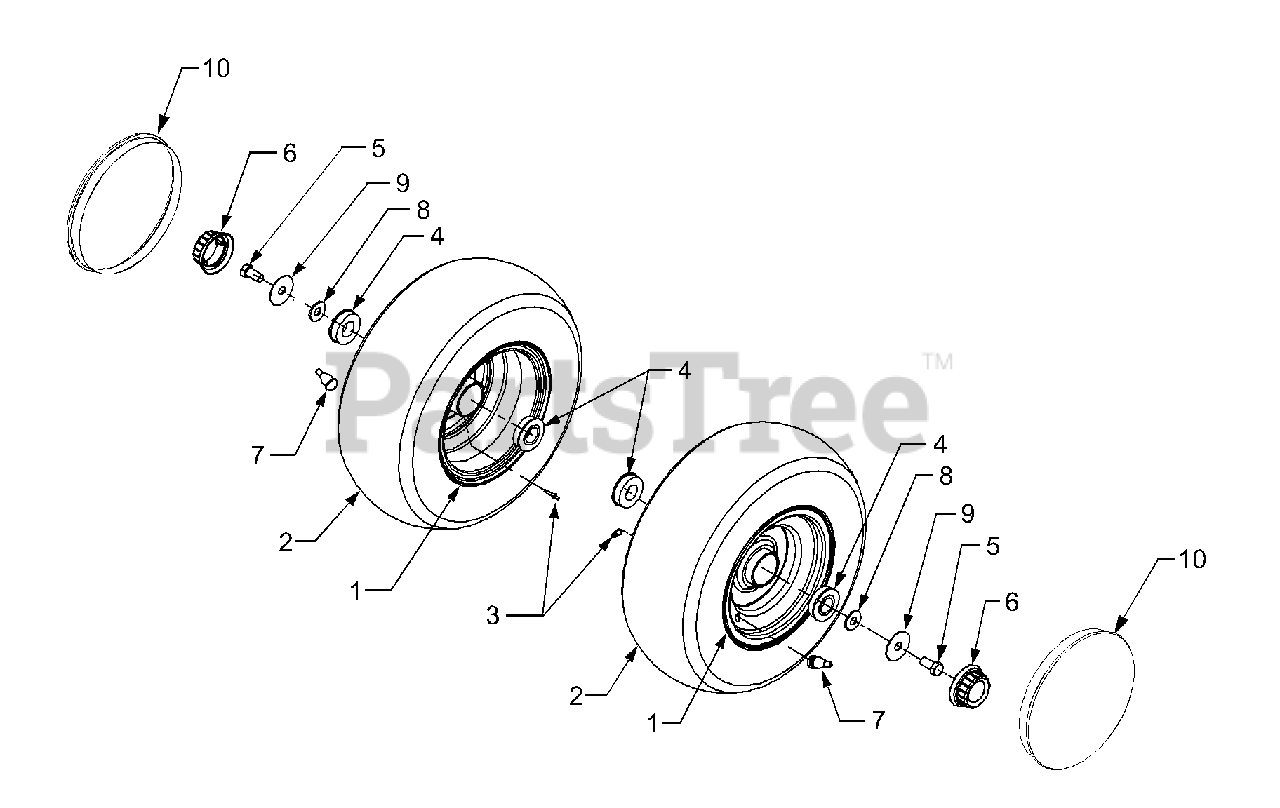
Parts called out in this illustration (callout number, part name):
1	Rim Assembly, Wheel
2	Tire, Turf, 16 x 7.5 x 8.0
3	Lube Fitting
4	Bearing, Ball
5	Screw, Hex Cap, 1/2-13 x 1.0 GR5
6	Hubcap
7	Valve, Tubeless Air
8	Washer, Flat, .531 x 1.25 x .1
9	Washer, Flat, .535 x 1.92 x .060
10	Hubcap, Front
